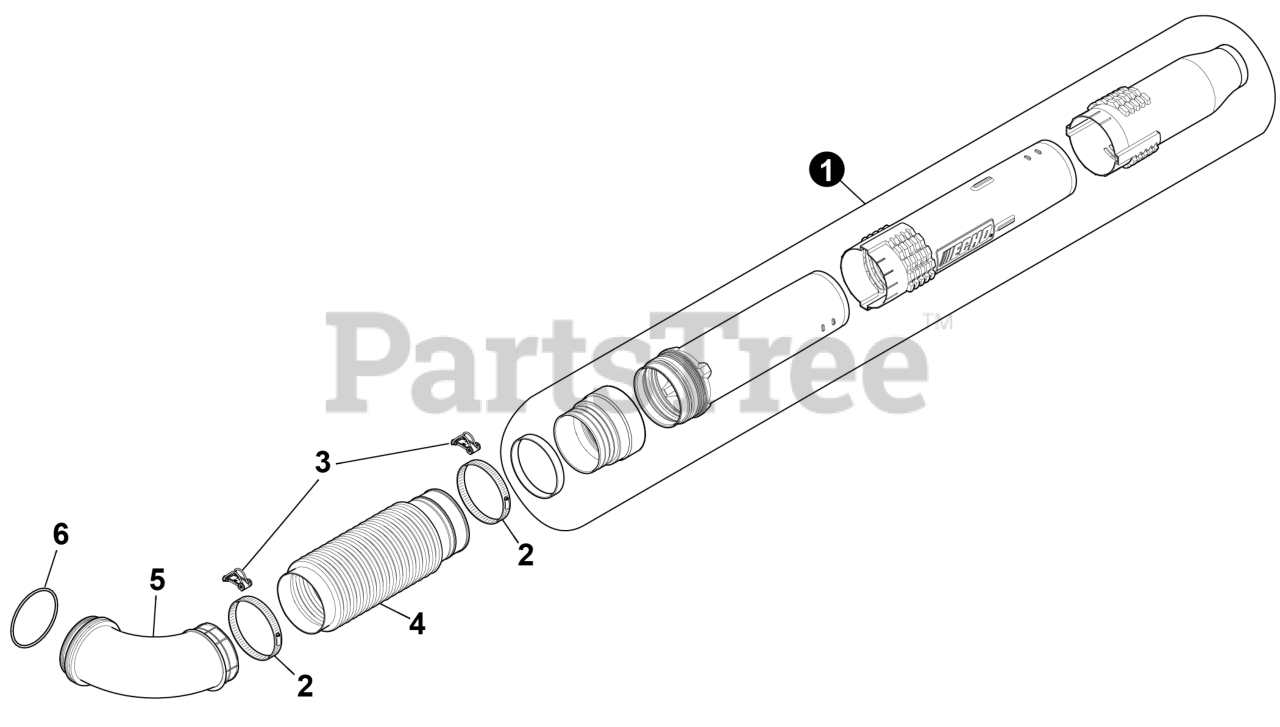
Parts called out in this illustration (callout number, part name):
1	TUBE ASSY,BLOWER
2	CLAMP,BLOWER TUBE
3	CLIP,CABLE
4	TUBE,FLEXIBLE BLOWER
5	TUBE,ELBOW BLOWER
